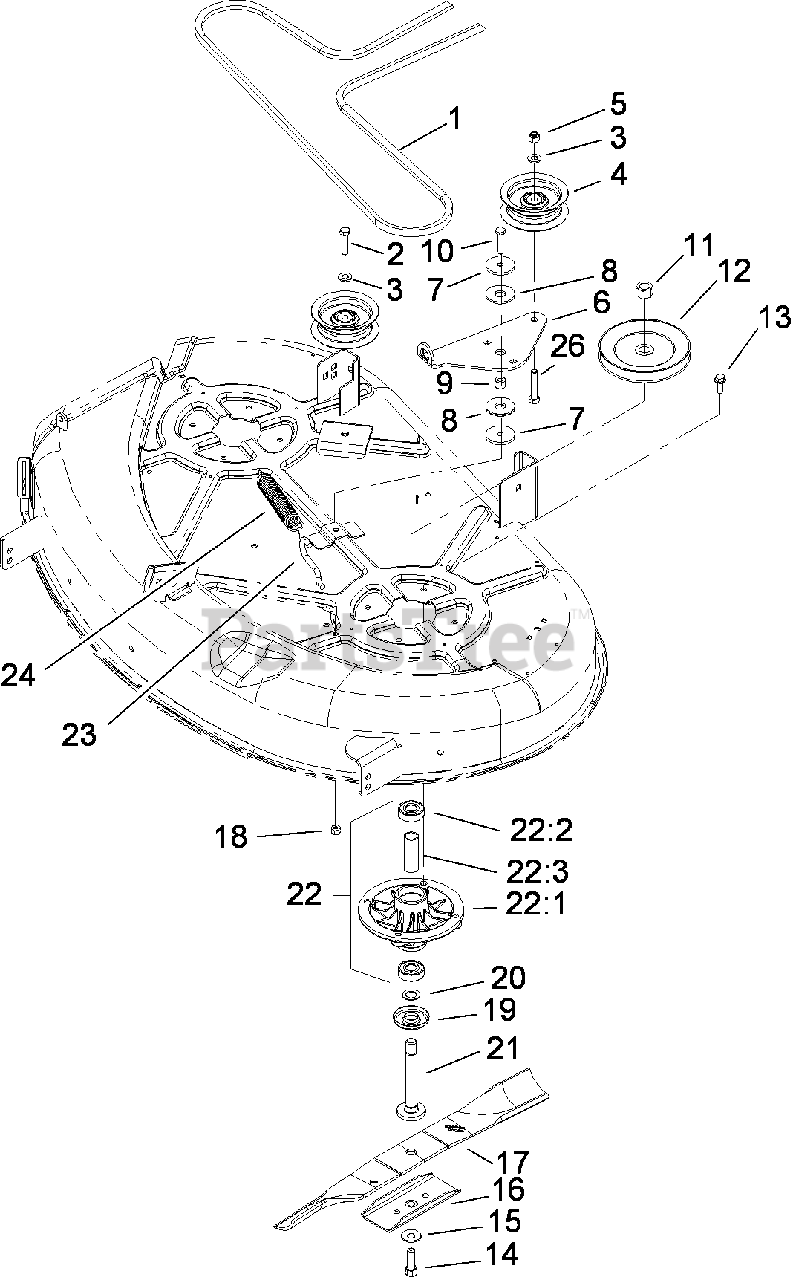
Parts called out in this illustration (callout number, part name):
2	SCREW-HH
3	WASHER-FLAT
4	PULLEY-IDLER, FLAT
5	NUT-LOCK, NI
6	ARM-IDLER
8	WASHER-FRICTION, COMPOSITE
10	SCREW-HH
11	NUT-HEX
12	PULLEY
13	SCREW-TAPTITE
14	SCREW-BLADE
15	WASHER-BELLEVILLE
16	STIFFENER-BLADE
17	BLADE-21.6 INCH
18	NUT-LOCK, NI
19	SHIELD-BEARING
21	SHAFT-SPINDLE
22	Spindle ASM
22:1	HOUSING-SPINDLE
22:2	BEARING-BALL
22:3	SPACER-BEARING
23	HOOK-RETURN, SPRING
24	SPRING-EXTENSION
26	SCREW-HH
